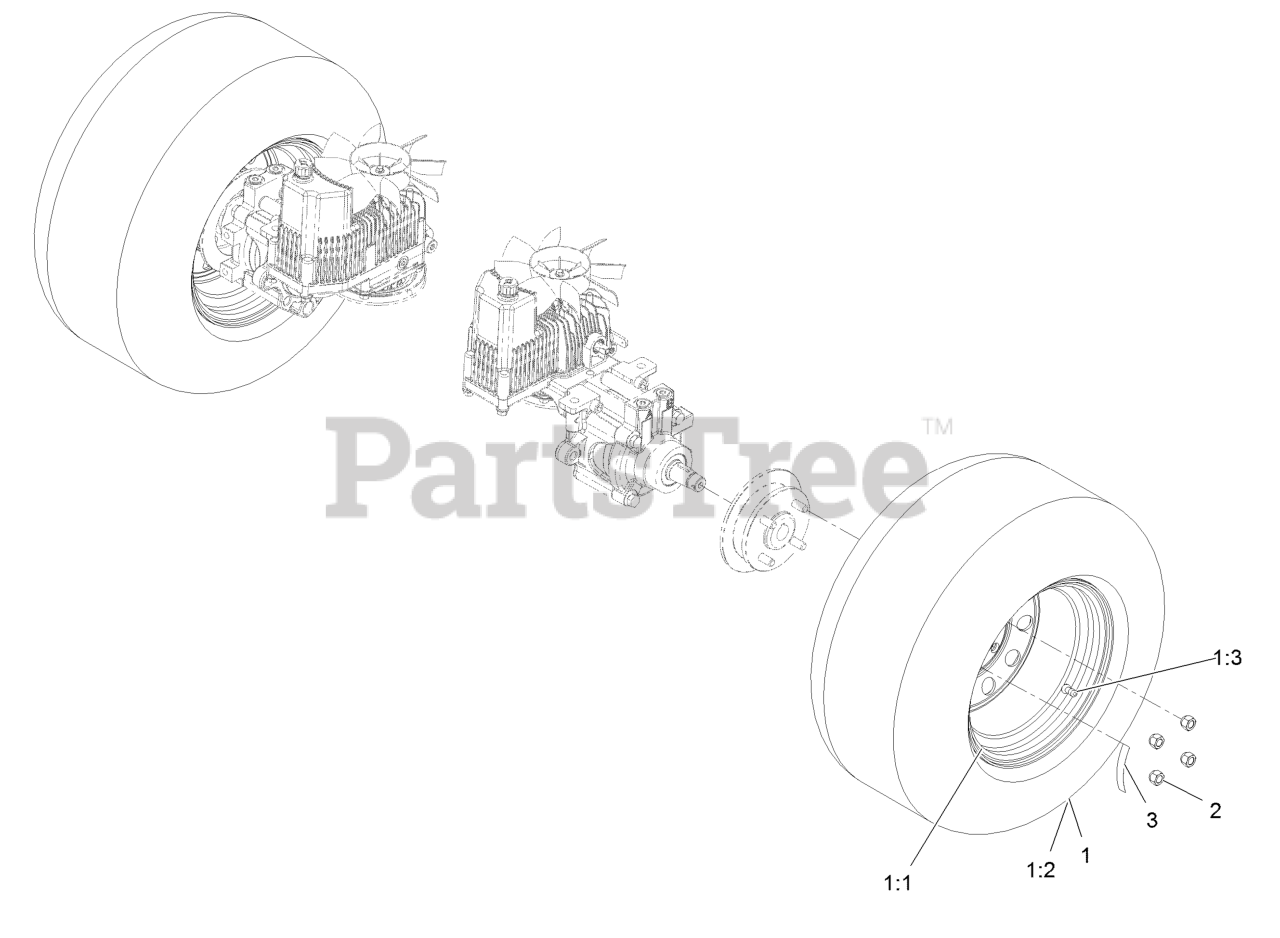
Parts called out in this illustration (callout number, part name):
1	WHEEL AND TIRE ASM
1:3	Stem-Valve
2	NUT-LUG
3	DECAL-TORQUE, WHEEL HUB LUG
